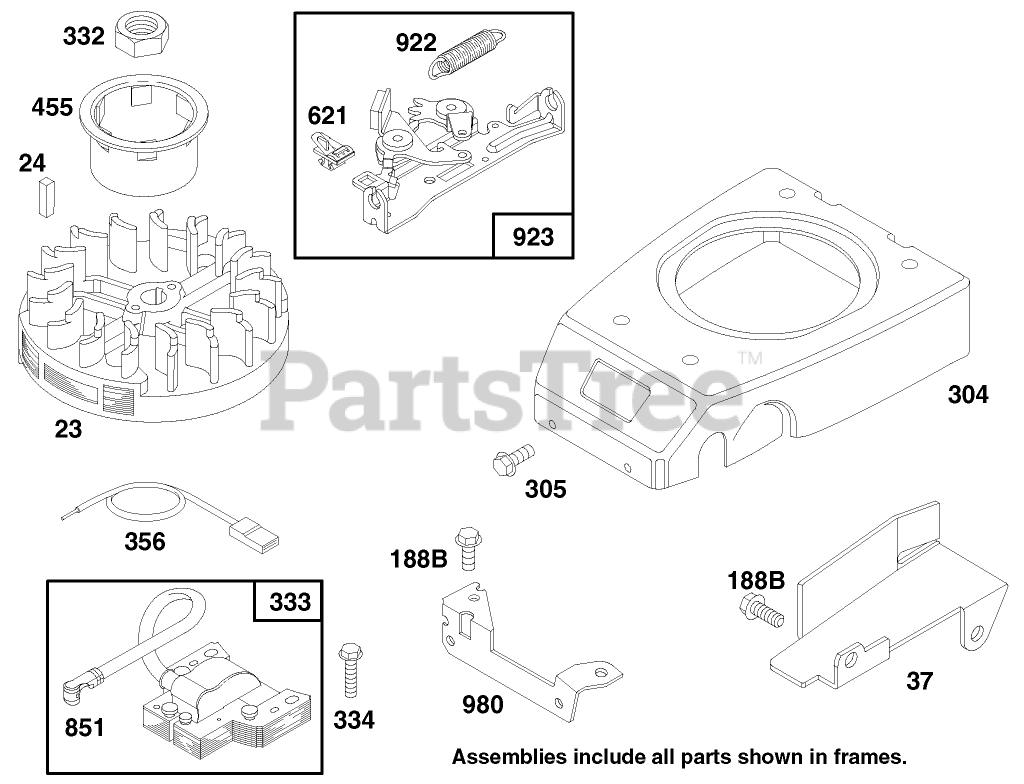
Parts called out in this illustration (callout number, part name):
24	KEY - FLYWHEEL
37	GUARD - FLYWHEEL
188B	SCREW - SEM
305	SCREW - HEX HEAD
332	NUT - HEXAGON
356	WIRE - GROUND
455	CUP - STARTER
621	STOP SWITCH
980	BRACKET-BLOWER HSG
